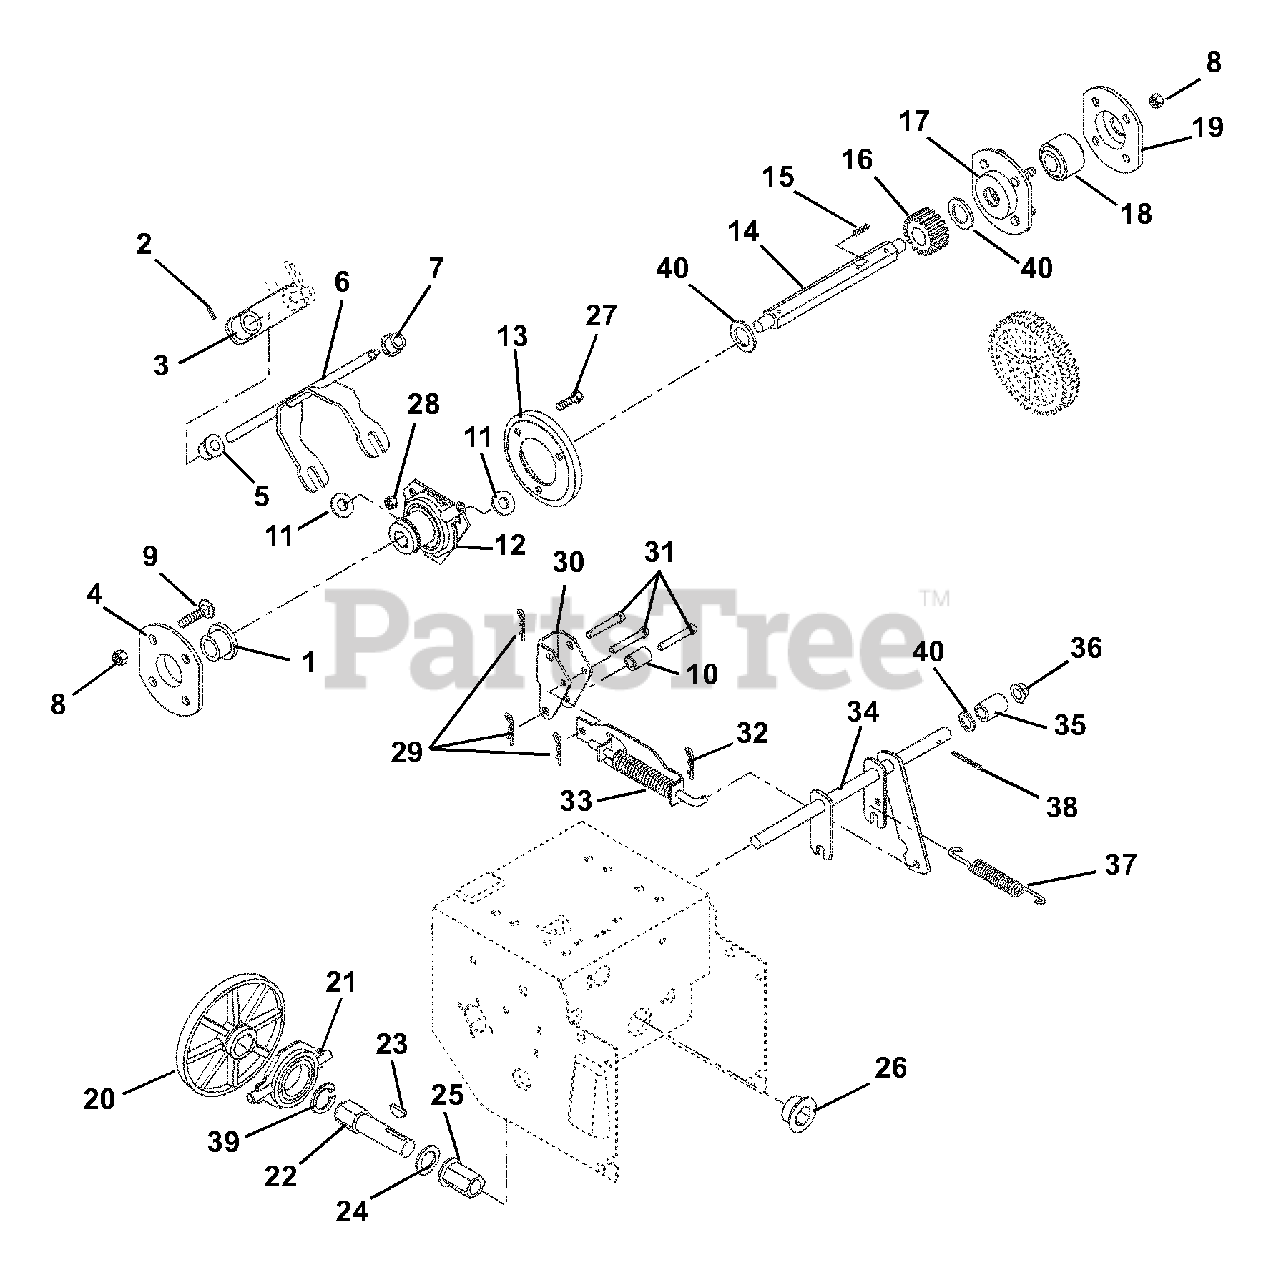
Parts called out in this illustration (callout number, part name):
1	BSHG-FLG .500X.750X.625X.937
2	PIN-ROLL .156X.88
3	ARM, SPEED CONTROL
4	FLANGE AND BUSHING
5	BSHG-FLG.500X.625X.312X.750NY
6	FORK-SPEED
7	BSHG-FLG .325X.444X.440X.560
8	NUT-LK-DUAL FACE 10-24 YWZC
9	BLT-RDHDSQSHK #10-24X.38 GR2YW
10	SPACER .322X.626X.50
11	WSHR-FL-STL .505X1.00X.062YWZC
12	SHIFT CARRIER
13	DISC, FRICTION - 730 MAT'L
14	HEX SHAFT
15	PIN-ROLL .125X.88
17	BEARING FLANGE
18	BRG-BALL .500X1.38X.437
19	BEARING FLANGE
20	FRICTION PLATE
21	BEARING ASSEMBLY
22	HEX SHAFT
23	KEY-WDRF .188X.75X.313 SAE 9
24	WSHR, THRUST .625X1.125X.063
25	BSHG-FLG .625X.875X1.750X1.188
26	BSHG-FLG .875X1.25X.75X1.50HX
27	@BLT-HEX .25-20X.50 GR5 YWZC
28	@NUT-LK-CTR .25-20 YWZC
29	PIN-HAIR INT .06X.18X.77
30	BRACKET, TRACTION ARM
31	PIN,CLEVIS .243/.248 X 1.38 YZ
32	PIN-HAIR INT .08X.18X1.18 YWZC
33	TRACTION CLUTCH ASSY
34	CLUTCH FORK
35	SPACER .504X.748X.321
36	CAP, .50 ROD YWZC
37	SG-TENS .063X.44X1.56
38	@PIN-CTR .12X1.00 EXTPRSQCT YZ
39	RG-RTNG-EXT 1.250X.050
40	@WSHR-FL-STL.531X1.06X.095YWZC
